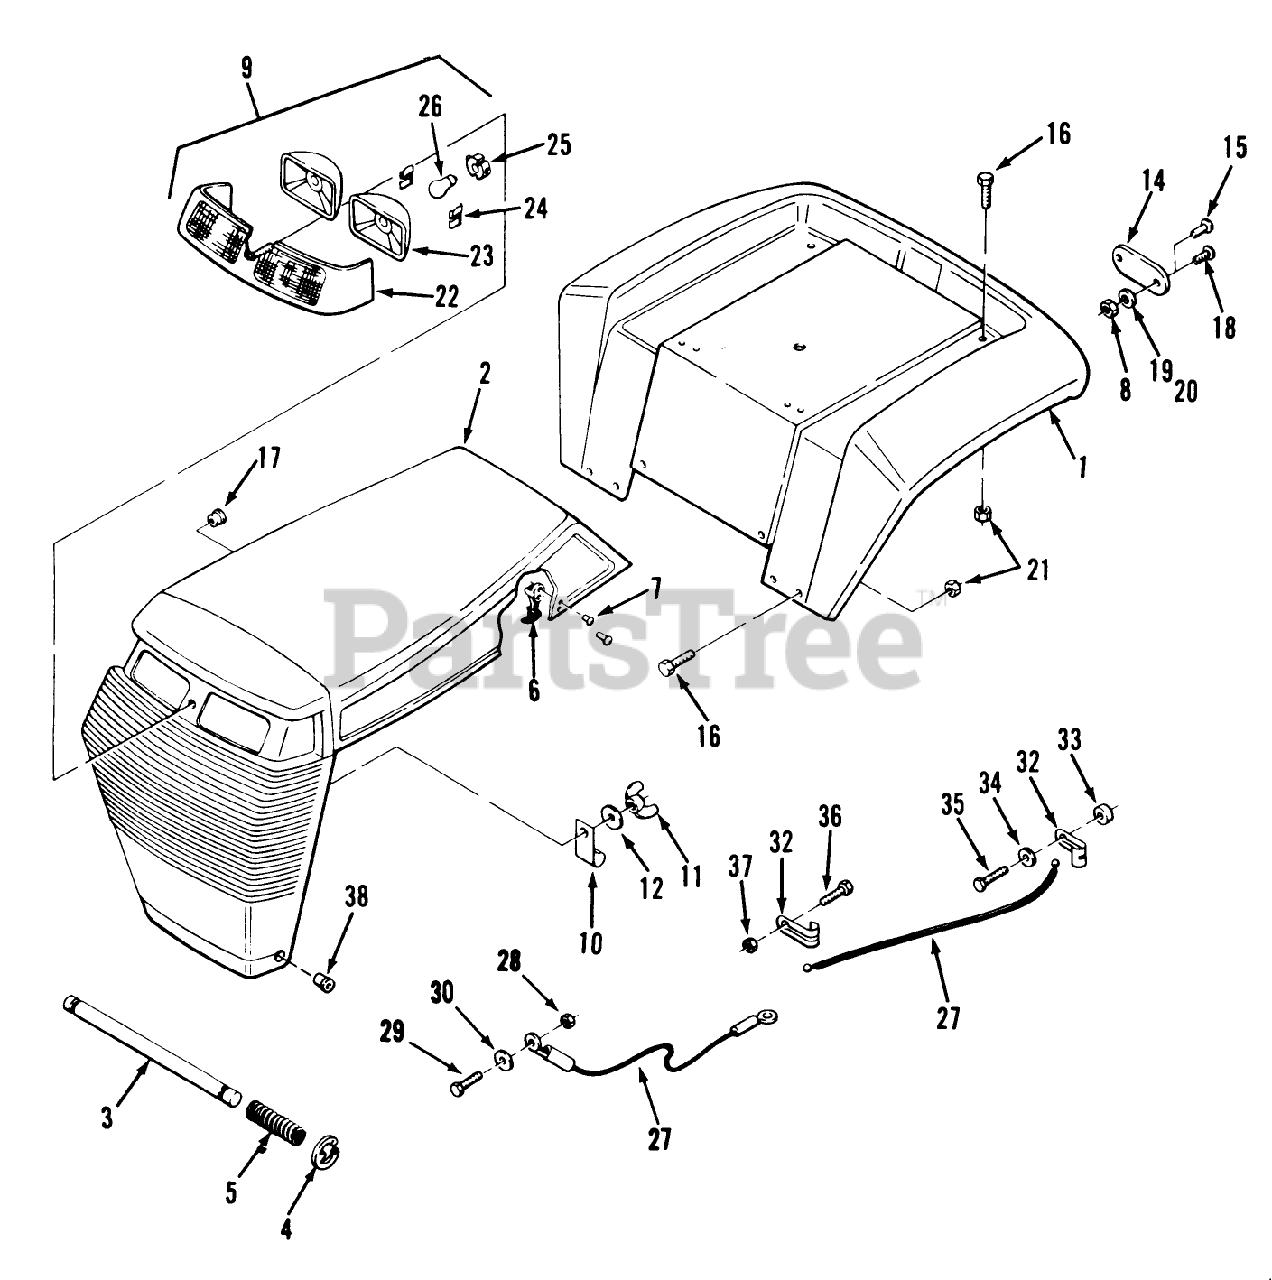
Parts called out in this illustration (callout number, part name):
1	FENDER *R
5	SPRING
6	HANDLE ASM
7	RIVET-POP
10	J-CLIP
11	WING NUT
12	WASHER
16	SCREW-CARR
17	BUSHING-NYLON 1.093
19	WASHER
23	LIGHT POD
24	RETAINER
25	SOCKET-HEADLIGHT
26	BULB
27	Hood Lanyard Cable
33	SPACER
38	NYLINER BUSHING
